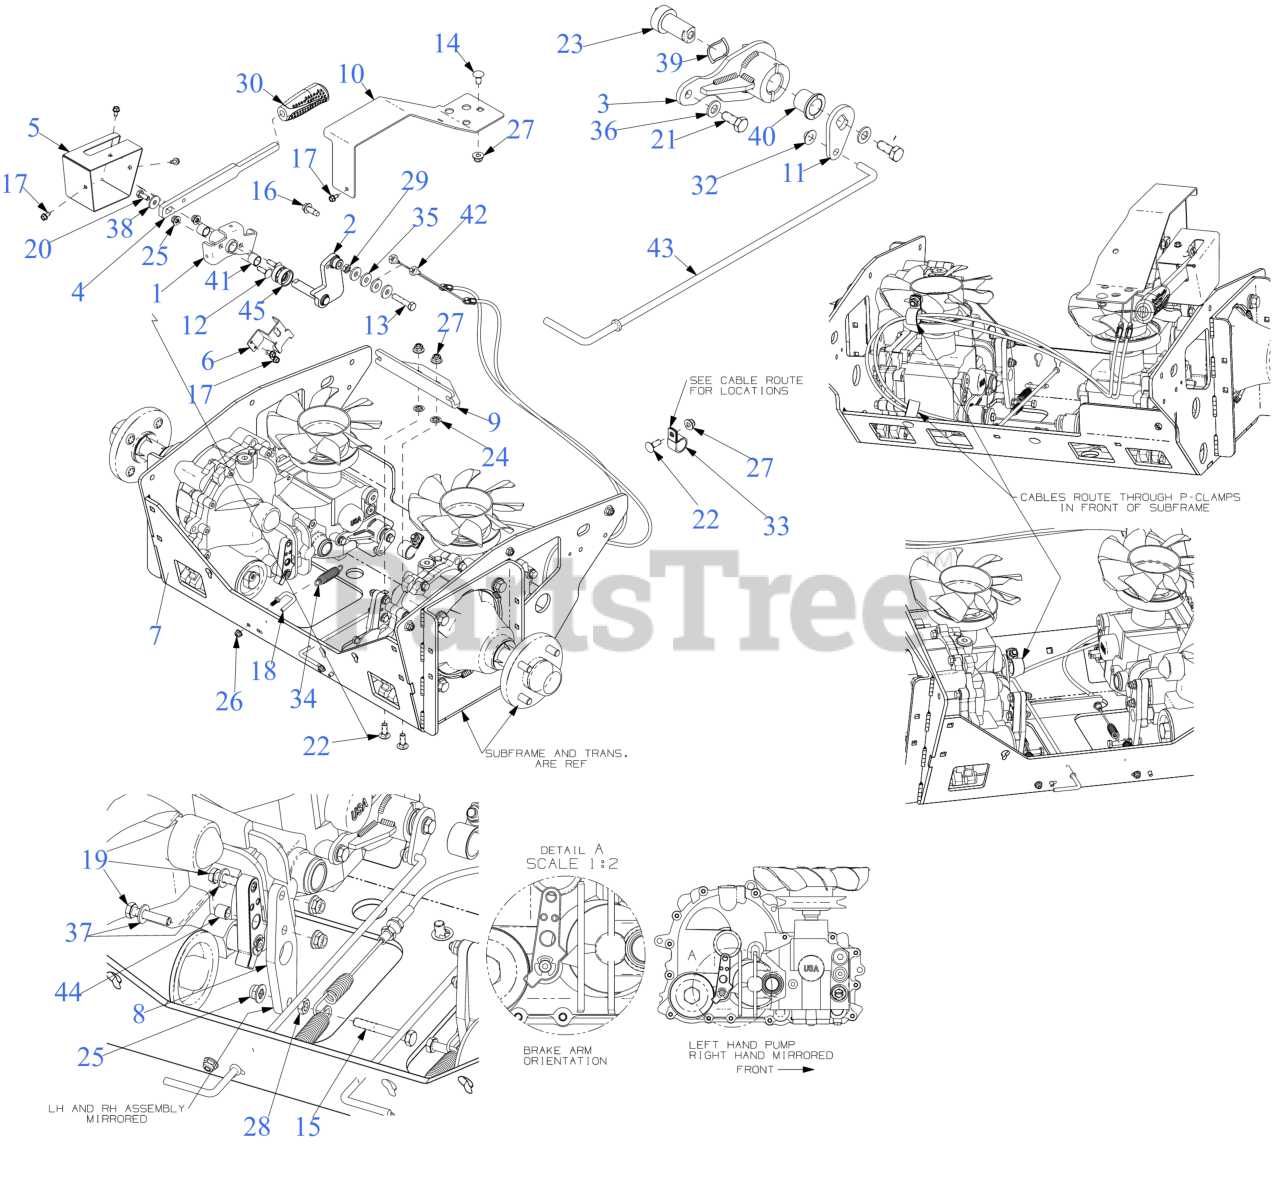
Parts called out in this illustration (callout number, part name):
1	PIVOT TUBE ASSEMBLY
2	BRAKE PIVOT SHAFT
3	ACTR ASM:BRKT:BYPASS
6	3-POLE SWITCH BRACKET
7	PLT:CNTR:SUPT:SUBFRAME:HG
8	BRAKE ARM PLATE
9	CABLE BRACKET
10	BRAKE LEVER COVER
11	BYPASS LEVER BRACKET
12	CARRIAGE BOLT 5/16-18 x 1.00
13	HEX SCREW 3/8-16 x 1.75 GR5
14	CARRIAGE BOLT 3/8-16 x .750 GR5
15	HEX SCREW 5/16-18 x 2.25 GR5
16	SCREW 3/8-16 x 1
17	SCREW 1/4-20 X.500
18	EYE BOLT SPRING GUIDE 1/4-20
19	SCREW 5/16-18 x 1.5 LG
20	SCREW 5/16-18 x .750
21	SCREW 5/16-18 x .75 GR5
22	CARRIAGE BOLT 3/8-16 x 1.00 GR5
23	ACTUATOR BYPASS SHAFT
25	FLANGE LOCK NUT 5/16-18
26	FLANGE LOCK NUT
29	HEX JAM NUT 3/8-16 GR5
33	HOSE CLAMP 1.0"
34	EXTENSION SPRING .65 OD x 2.65 LG
35	FLAT WASHER .385 x 1.00 x .135
36	FLAT WASHER
37	FLAT WASHER
38	FLAT WASHER 1.0 OD:.331 ID
39	WAVE WASHER .785X1.00X.012
40	FLANGE BEARING .625 X .75 X .75
41	SLEEVE BEARING
42	PARK BRAKE CABLE
43	BYPASS ROD
